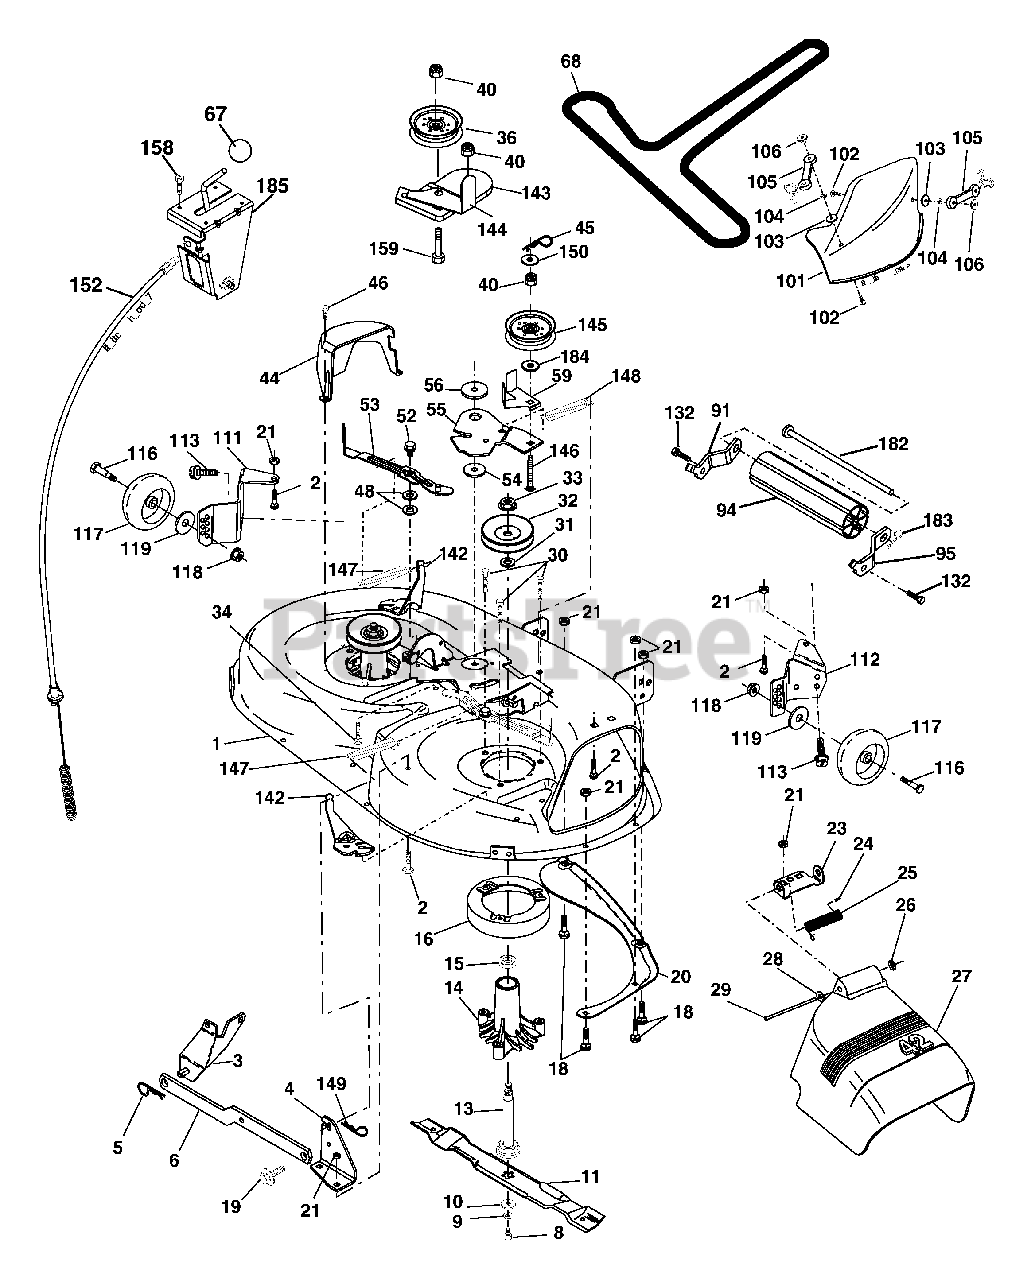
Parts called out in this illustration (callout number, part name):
1	Mower Deck Assembly, 42"
2	Bolt
3	Bracket Asm Fr. Sway Bar 3/42
4	Bracket Asm Deck 42" Sway Bar
5	Retainer Spring
6	Bar Sway Deck
8	Bolt 3/8-24 x 1.25 Gr. 8 patched
9	Washer, Lock
10	Washer, Hardened
11	Blade Mower 42" Hi-Lift
11	Blade, Mulching 42" Premium
11	Blade Mulching 42" Premium
13	Shaft Assembly, Mandrel, Vented
14	Housing, Mandrel, Vented
15	Bearing, Ball, Mandrel
16	Stripper, Mandrel Deck
18	Bolt, Carriage 5/16-18 x 5/8
19	Bolt, Shoulder
20	Baffle, Vortex
21	Nut
23	Bracket, Deflector Mower 42"
24	Cap, Sleeve 80 x 112 Blk Mower
25	Spring, Torsion, Deflector 2 52
26	Nut, Push Phos & Oil
27	Shield, Deflector 42" Blk
28	Washer 11/32 x 5/8 x 16 Ga.
29	Rod, Hinge 42" 6 75 W/G
30	Screw Thdrol
31	Washer, Spacer Mower Vented
32	Pulley, Mandrel
33	Nut, Toplock
34	Bolt Carr SH 3/8-16 x 1-1/2 Gr.5
36	Pulley, Idler, Flat
40	Nut Lock 3/8-16
44	Guard, Mandrel, LH
45	Retainer
46	Screw, Thdrol 1/4-20 x 5/8 T
48	Washer, Hardened
52	Bolt, Shoulder 5/16-18 unc
53	Arm Assembly, Pad, Brake
54	Washer, Hardened
55	Arm, Idler
56	Spacer, Retainer
59	Guard TUV Idler
67	Knob Round
68	V-Belt, 42" Mower
91	Bracket Roller Nose LH
94	Roller Nose
95	Bracket Roller Nose RH
101	Mulcher Cover
102	Screw, Pan Hd Phillip 10-24 x 5/8
103	Washer, Flat
104	Washer, Lock
105	Latch Assembly
106	Nut, Weld
111	Bracket Asm. Whl Ga. LH
112	Bracket Asm Whl Ga. RH
113	Screw 5/16-18
116	Bolt, Shoulder
117	Wheel, Gauge
118	Nut Centerlock 3/8-16
119	Washer 3/8 x 7/8 x 14 Ga.
132	Screw 3/8-16 x 3/4
136	Bar Adjusting Gauge Wheel
142	Arm Spring Brake Mower
143	Bracket Arm Idler 42"
144	Keeper Belt 42" Clutch Cable
145	Pulley Idler Flat
146	Bolt Carriage Idler
147	Spring Extension
148	Spring Return Idler
149	Retainer Spring Yellow
150	Washer 9/32 x 3/4 x 10 Ga.
152	Clutch Cable 42"
158	Screw Hex Thd Cut 1/4-20 x 1/2
159	Bolt Rdhd Sqn 3/8-16 unc x 1-3/4
182	Rod Roller Nose
183	Retainer Spring
184	Washer 13/32 x 7/8 x 10 Ga.
185	Head Asm Cable Clutch
